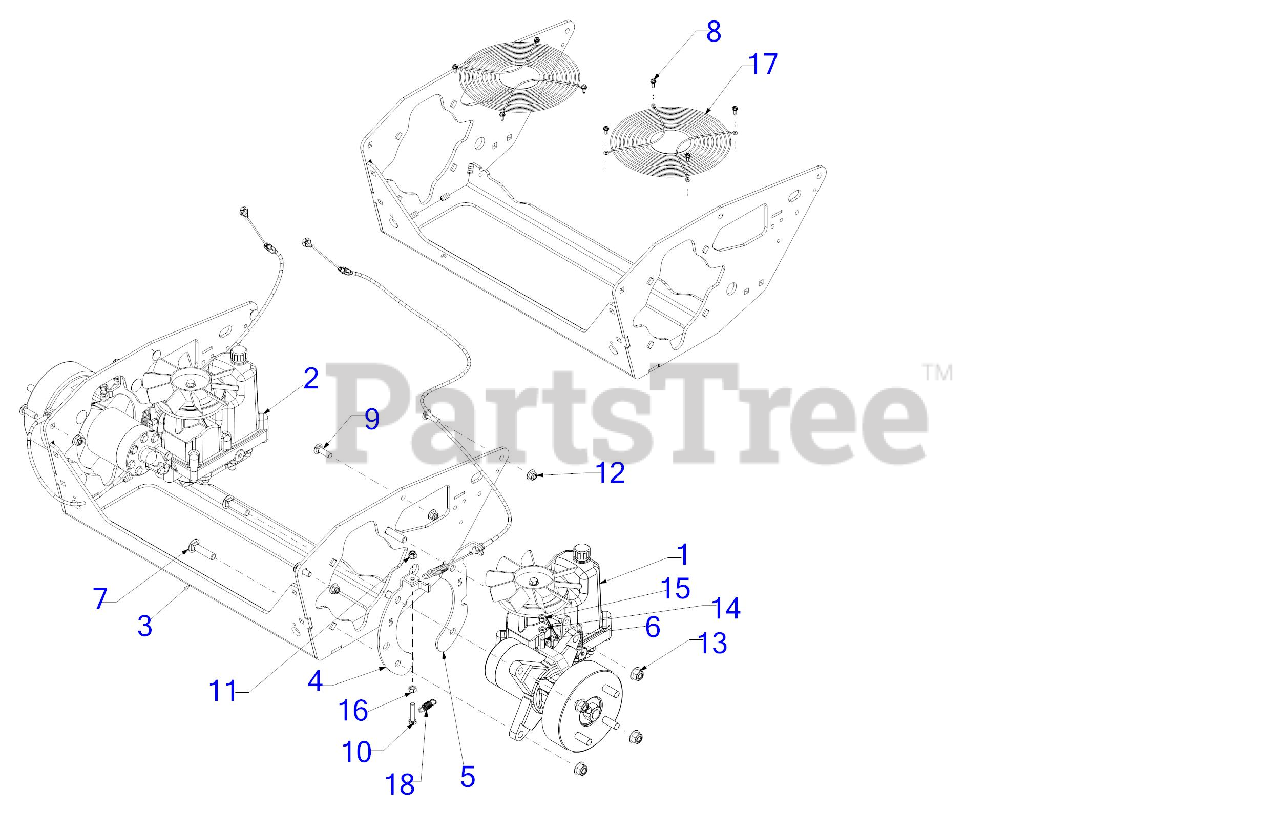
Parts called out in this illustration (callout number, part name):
1	TRANSMISSION / MOTOR ASSEMBLY (RH)
2	TRANSMISSION / MOTOR ASSEMBLY (LH)
6	SCREW 5/16-18 x 1.0 GR5
7	CARRIAGE BOLT 1/2-13 GR5
8	SCREW 10-24 x 0.500
9	CARRIAGE BOLT 3/8-16 X1.25 GR5
10	SCREW 5/16-18 x 1.5 LG
11	FLANGE LOCK NUT 5/16-18
15	HEX NUT
16	HEX NUT
18	EXTENSION SPRING .500 OD x 1.71
